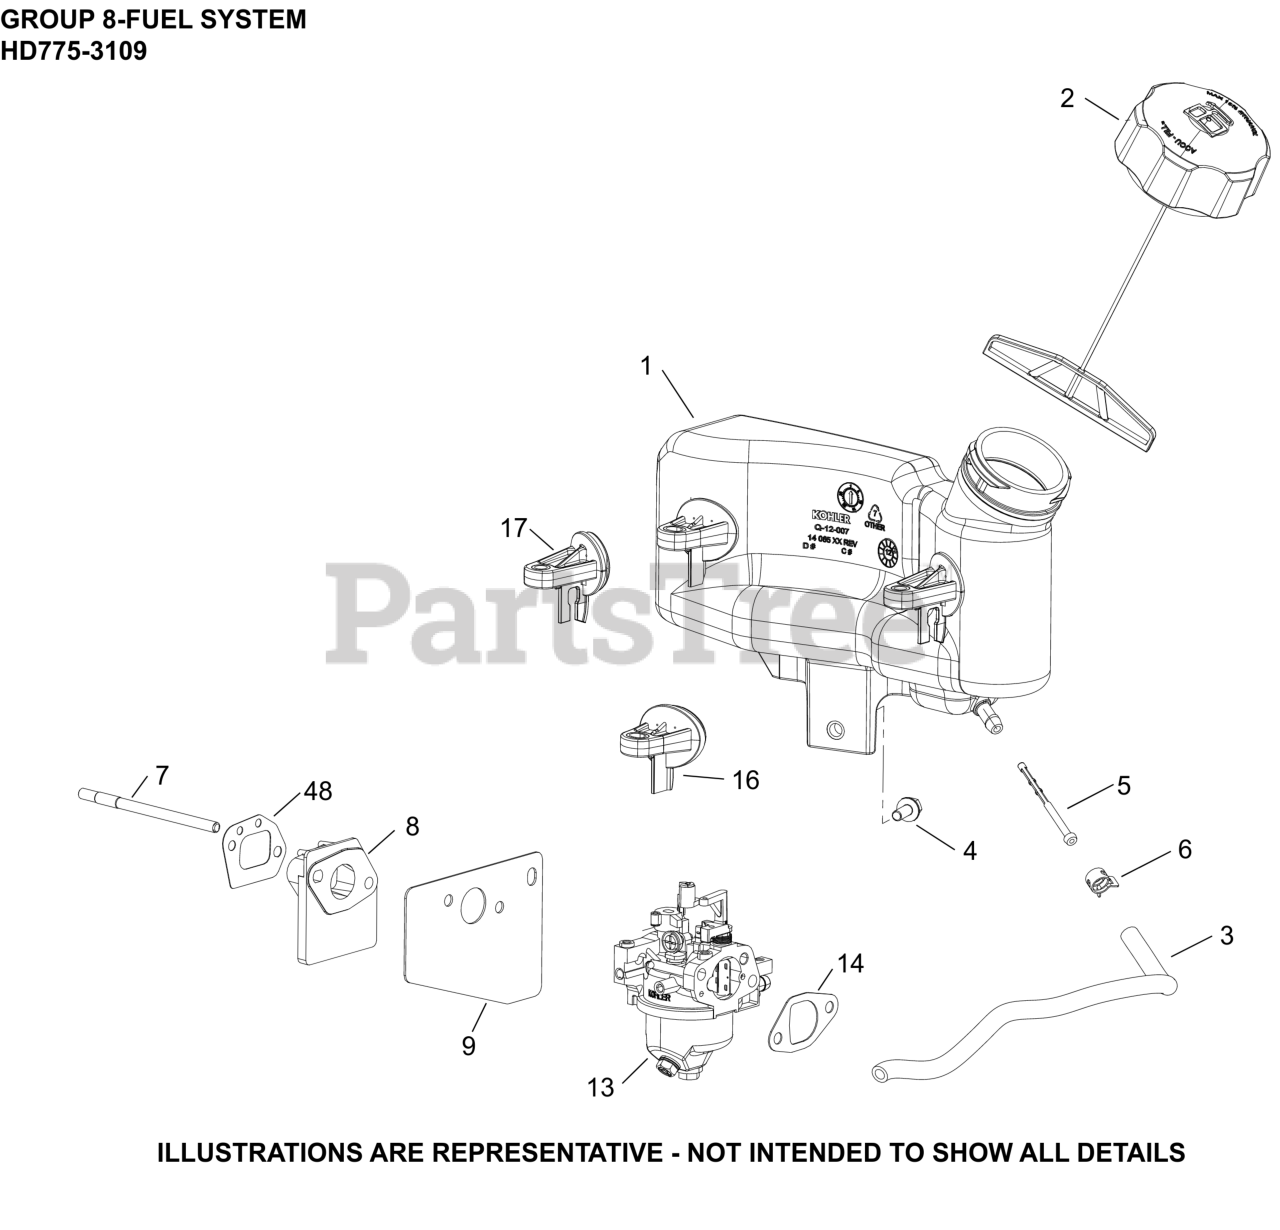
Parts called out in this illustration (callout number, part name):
1	TANK, FUEL
2	FUEL CAP ASSEMBLY
3	HOSE, FUEL LOW-PERMEATION
4	SCREW, HEX FLANGE (M6)
5	FILTER, FUEL IN-NIPPLE
6	CLAMP, HOSE (NON-CALIF)(#1423710S)
7	STUD,M6X1.0X100.2MM
8	KIT, SPACER
9	KIT, CARBURETOR HEAT SHIELD GASKET
13	KIT, CARBURETOR 13 MM STD CHOKE
14	KIT, INTAKE GASKET
16	BRACKET, FUEL TANK-DISCONTINUED
17	BRACKET, FUEL TANK-DISCONTINUED
48	GASKET SPACER
NI	KIT,HIGH AL(4000-8000 FT)USE 14 755 04-S
NI	KIT, CARBURETOR REPAIR (RUIXING)
